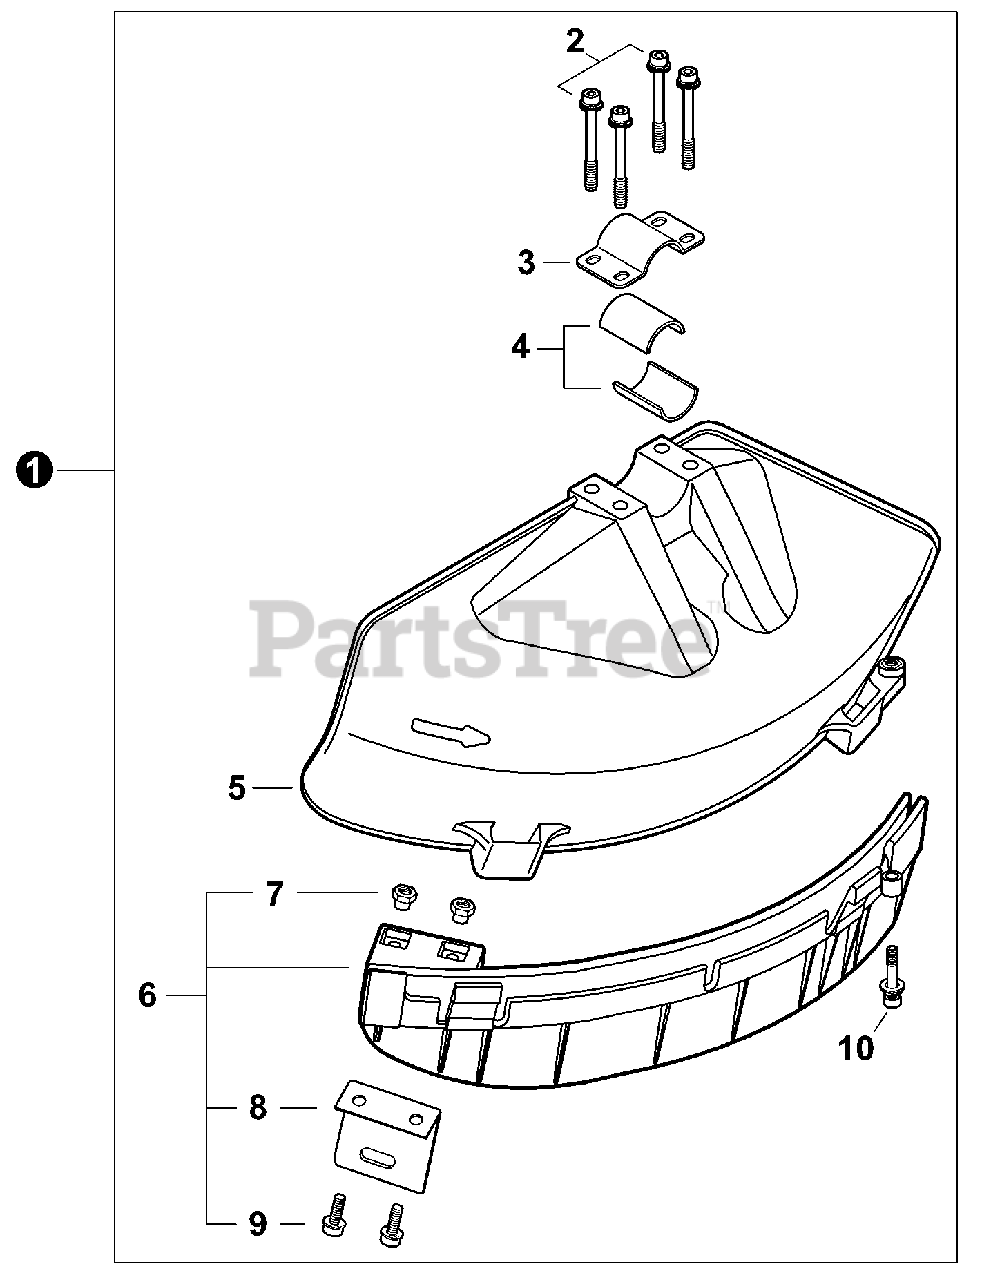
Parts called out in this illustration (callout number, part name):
1	DEBRIS SHIELD KIT
2	BOLT M5×45
3	CLAMP, UPPER
4	SPACER 24
5	SHIELD, DEBRIS - BLADE
6	DEBRIS SHIELD EXTENSION ASSY
9	BOLT 5×16
10	BOLT M5×22
